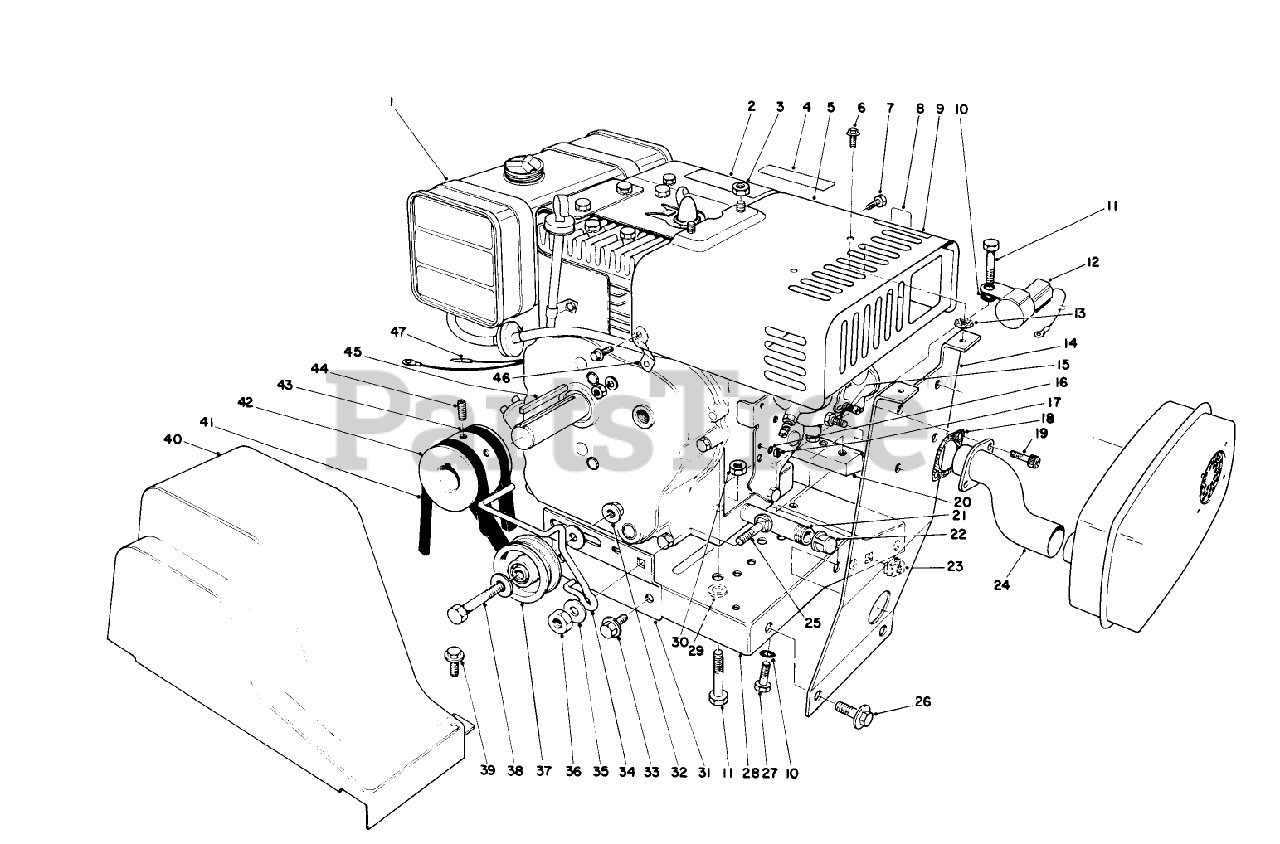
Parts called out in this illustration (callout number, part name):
1	Engine
2	CAUTION DECAL
3	NUT-HEX, SIDE DEFORM
4	DECAL SYNCHRO BALANCE
5	Heater Box
6	SCREW-HWH
8	CHOKE DECAL
9	HOT SURFACE DECAL
10	WASHER-LOCK, INTERNAL
11	SCREW-HH
12	INTERLOCK MODULE
13	Washer
14	Muffler Mounting Bracket
15	1/4-20 X 1/2 SEMS MS
16	WASHER-LOCK/INT
17	NUT-LOCK
18	Gasket
19	SCREW-HSH
20	Block Engine Mounting
21	NIPPLE-PIPE
22	CAP-PIPE
23	RETAINER NUT
24	EXHAUST PIPE
25	SCREW-CARR
26	SCREW-HH
27	SCREW-HH
28	Engine Base
29	WASHER-PLAIN
30	NUT-LOCK, NI
31	BELT IDLER BRKT
32	NUT-HHF, WHIZ
33	SCREW-HHFTF
34	BELT GUIDE
35	WASHER-FLAT
36	NUT-LOCK, NI
37	PULLEY B
38	SCREW-HH
39	SCREW-HWH
40	BELT GUARD
41	V-BELT
42	ENGINE PULLEY
43	V-BELT
44	Screw-Set
46	Brace Heater Box
